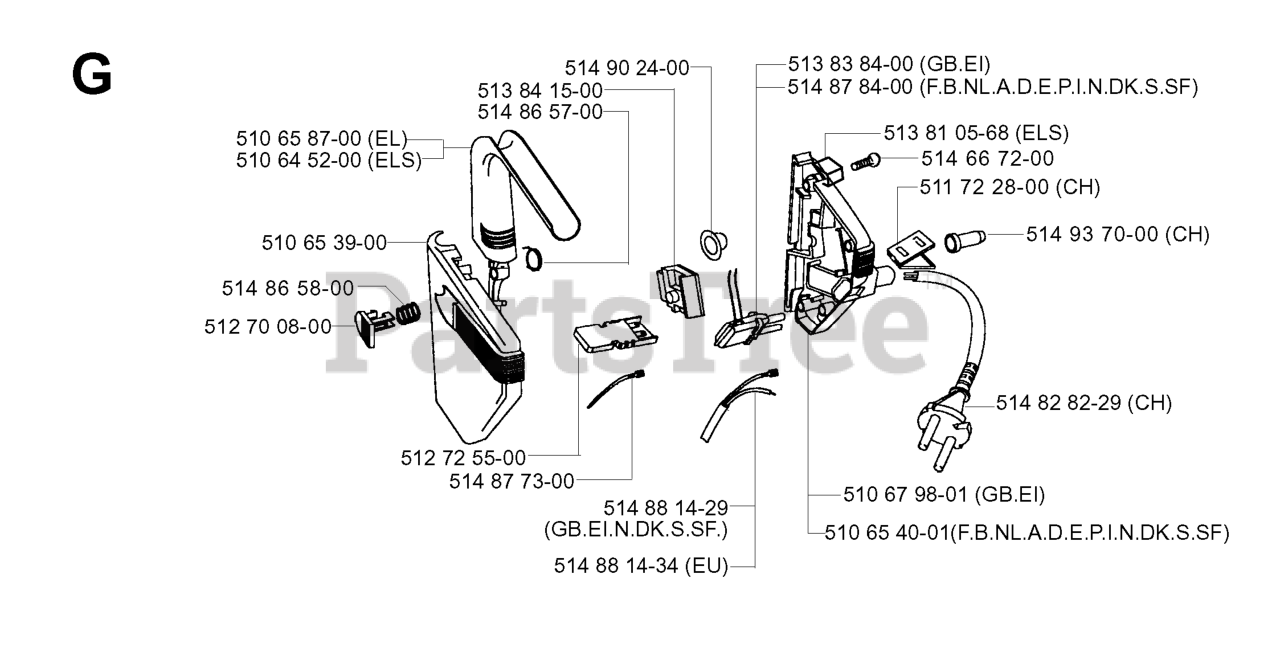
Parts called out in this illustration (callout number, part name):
1	PLATE.PNT.ENGINE.E-DIP
2	PLATE, IDLER, BLK
3	PULLEY, V, 1.125 BORE
4	IDLER PULLEY
5	PULLEY.IDLER.FLAT.46.PR.DR.
6	BELT, HYDRO, 3400
7	PIVOT, IDLER
8	PIVOT, BEARING
9	ARM, IDLER, STEEL, W/BGS
10	CLUTCH 200 FT LB
11	STOP, CLUTCH, BLACK
12	CABLE POSITIVE
13	MUFFLER.26HP.KAW.FX651V-730V
14	SOLENOID.STARTER.BRASS.PLUNGER
15	SPRING, PUMP
16	SHIELD, DUST
17	DUST SHIELD
18	SHIELD MUFFLER
19	HOSE.ASSEMBLY.OIL.DRAIN
20	ADAPTER, OIL DRAIN
22	PLUG, DRAIN 3/8 NPTF
23	KEY, 1/4 SQ X 1 1/4
24	GASKET.EXHAUST.KAWASAKI
26	TERMINAL COVER
27	U-CLIP 5/16-18 NUT RETAINER
28	BOLT.3/8-14X1.25
29	RHSNB 3/8-16 X 2.75
31	CLUTCH BOLT7/16-20X2.5 GR596HR
32	HCS 1/2-13 X 3-1/4 GD 5 ZD
33	HHFS 3/8-16 X 2.0 GD 5
34	HHFS 5/16-18 X 3/4
35	HCS 1/4-20.
36	HCS 3/8-16X1.GRD.5.ZD
37	HCS 5/16C X 1
38	RP_SCREW.1/4-20X3/8
39	NUT 3/8C WHIZ
40	5/16-18 NYLOC FLANGE NUT
41	NUT, 1/2-13 HEX FLG NYLOC ZD
42	NUT HEX 3/8-16 NYLON, THIN
43	NUT 3/8-16 HEX FLG NYLOC ZD
44	JAM NUT 1/4C (2 2 PW01)
45	WASHER 1/4 INT TOOTH
46	CONTACT BELLSPR 1/2
47	WASHER 7/16 LOCK
48	WASHER 3/8 X 3/4 X .187 TK
49	WASHER
50	WASHER.9/16 X 1 3/8 X 12 GA.
51	WASHER, 3/8 SPEC
52	RP WASHER 3/8 FLAT
53	SLW 3/8 STD
